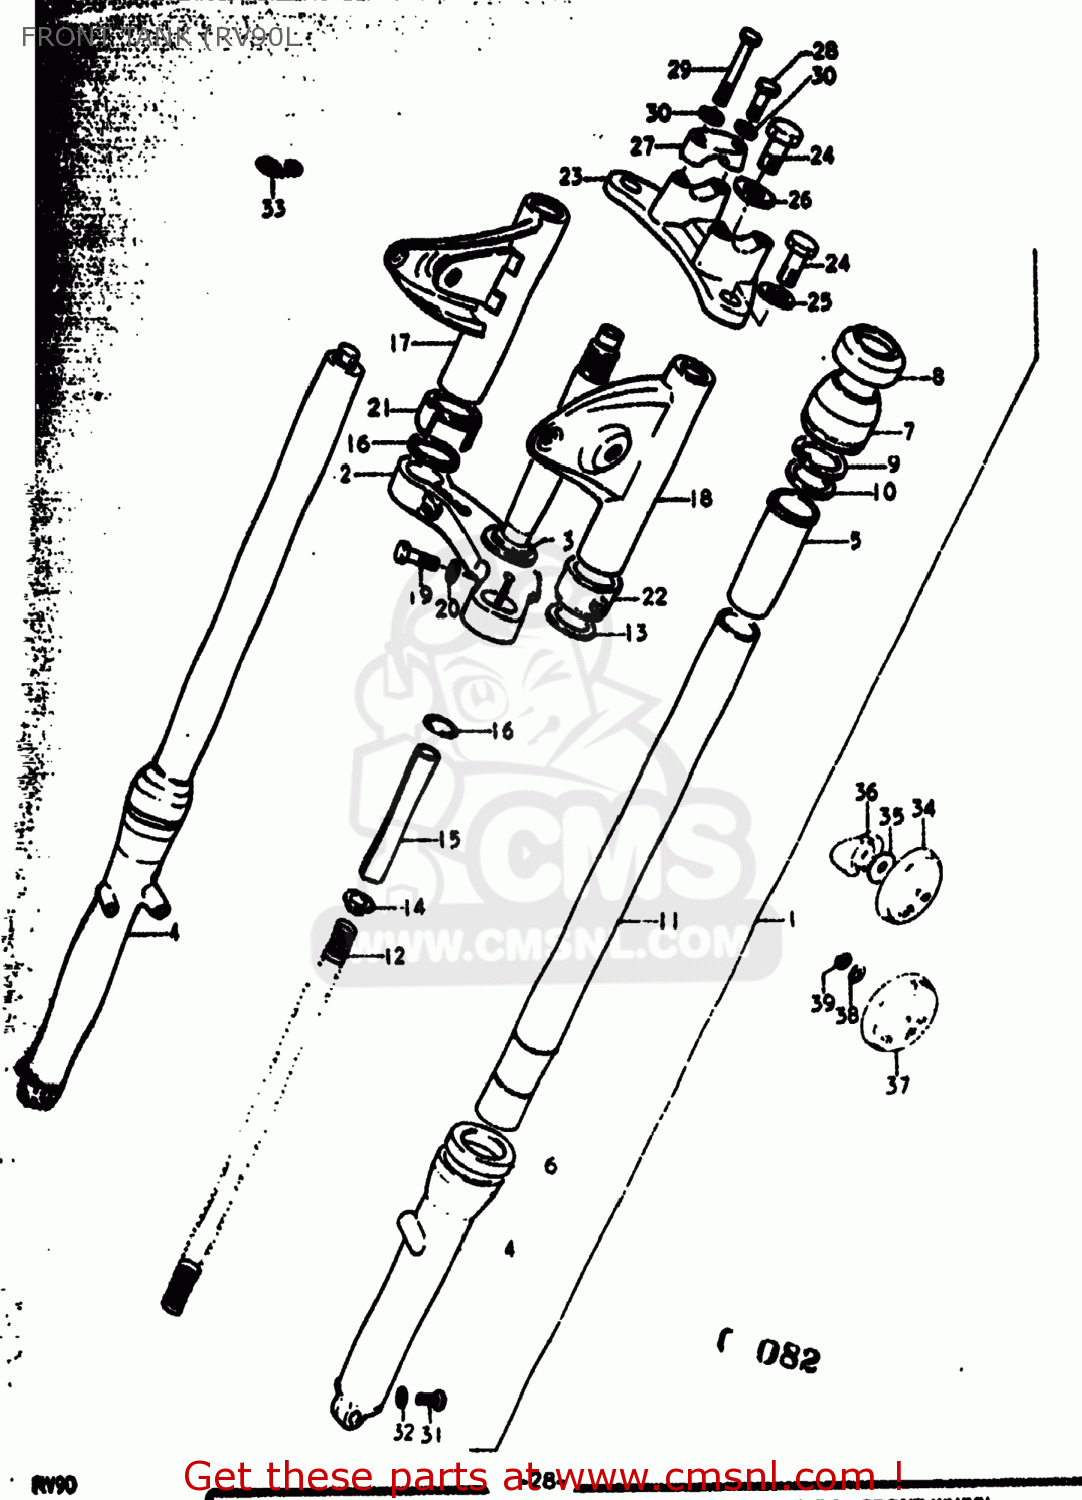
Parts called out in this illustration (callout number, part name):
1	DAMPER SET
2	STEM,STEERING
3	RACE,STEERING OUTER LWR
4	TUBE,FORK,OUTER,RIGHT
5	GUIDE,FRONT FORK TUBE
6	OIL SEAL,FRONT FORK
7	SEAL,DUST
8	BAND,FRONT FORK COVER
9	CIRCLIP
10	RING,FORK BACK UP
11	TUBE,INNER
12	SPRING,FRONT FORK
13	CUSHION,HEADLAMP BRACKET
14	GUIDE,FRONT FORK SPRING C
15	SPACER,FRONT FORK SPRING
16	O RING
17	BRACKET,HEADLAMP HOUSING
18	BRACKET,HEADLAMP,LEFT
19	Bolt 10X40
20	LOCK WASHER
21	COVER STEM RH
22	COVER STEM LH
23	HEAD,STEERING STEM
24	BOLT,FORK INNER TUBE
25	WASHER
26	WASHER,STEERING STEM
27	HOLDER,HANDLEBAR
28	Bolt
29	BOLT
30	LOCK WASHER
31	SCREW
32	GASKET,DRAIN,PLUG (NAS)
33	GUIDE,CABLE
34	REFLEX REFLECTOR ASSEMBLY
35	WASHER (6.5X20X1.2)
36	SPACER
37	REFLEX REFLECTOR,FR
38	WASHER
39	LOCK WASHER
